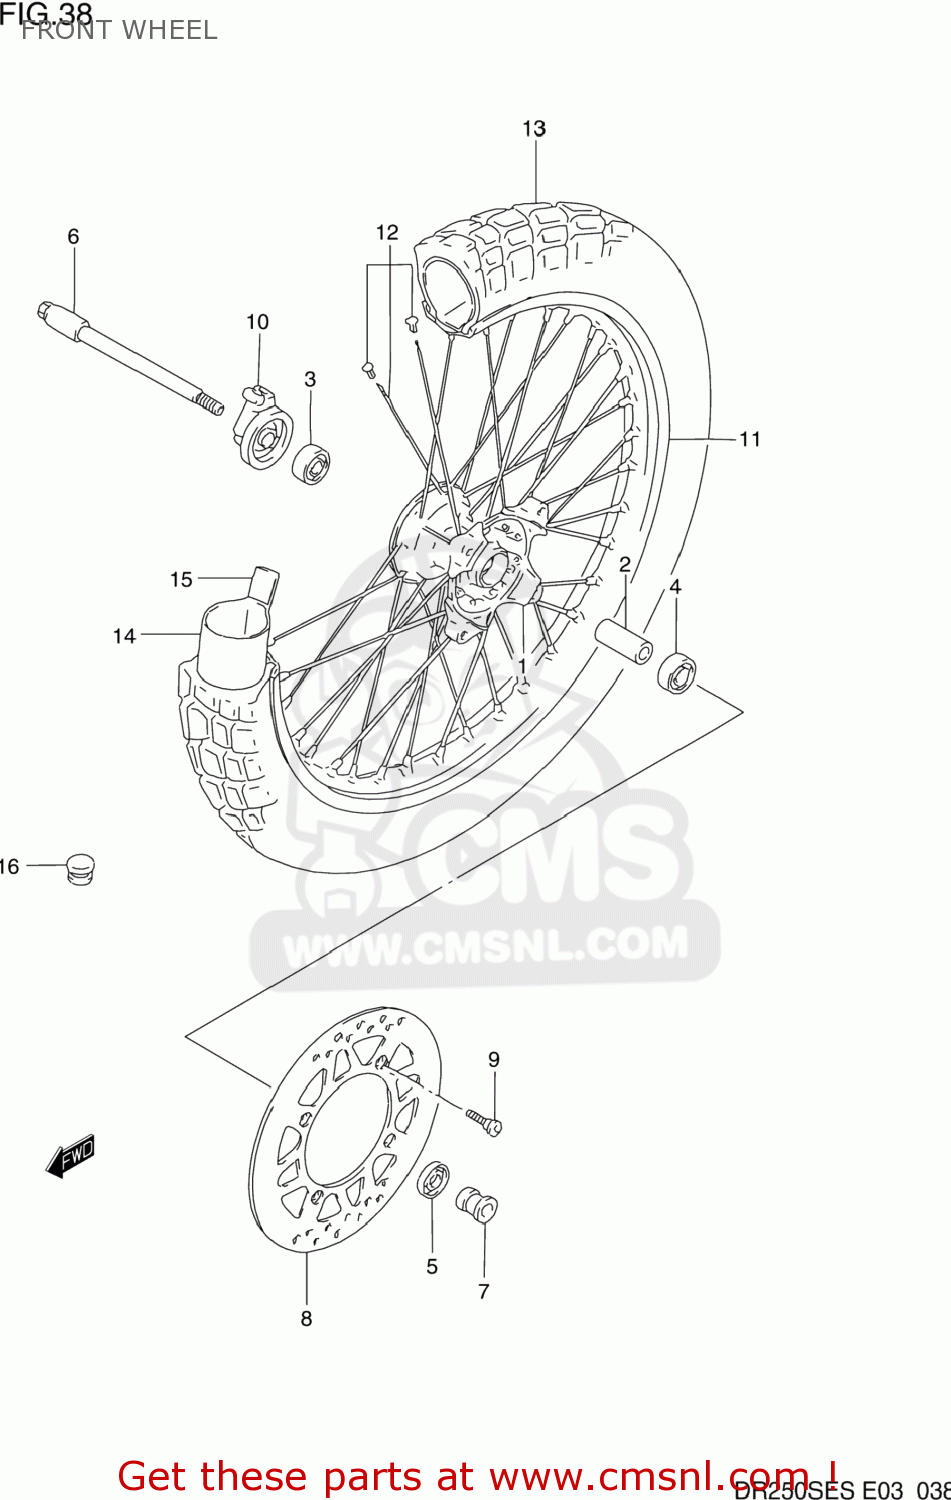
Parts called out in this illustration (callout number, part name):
1	HUB,FR WHEEL
2	SPACER,FR HUB BEARING
3	BEARING
4	BEARING
5	SEAL,OIL(22X35X5)
6	AXLE,FR
7	SPACER,FR AXLE,L
8	DISC,FR BRAKE
9	BOLT,BRAKE DISC
10	BOX ASSY,SPEEDOMETER GEAR
11	RIM,FR WHEEL(1.60X21)
12	SPOKE SET,FR WHEEL
13	TIRE,FRONT
14	TUBE
15	PROTECTOR,WHEEL INNER
16	CAP(OD:12)
